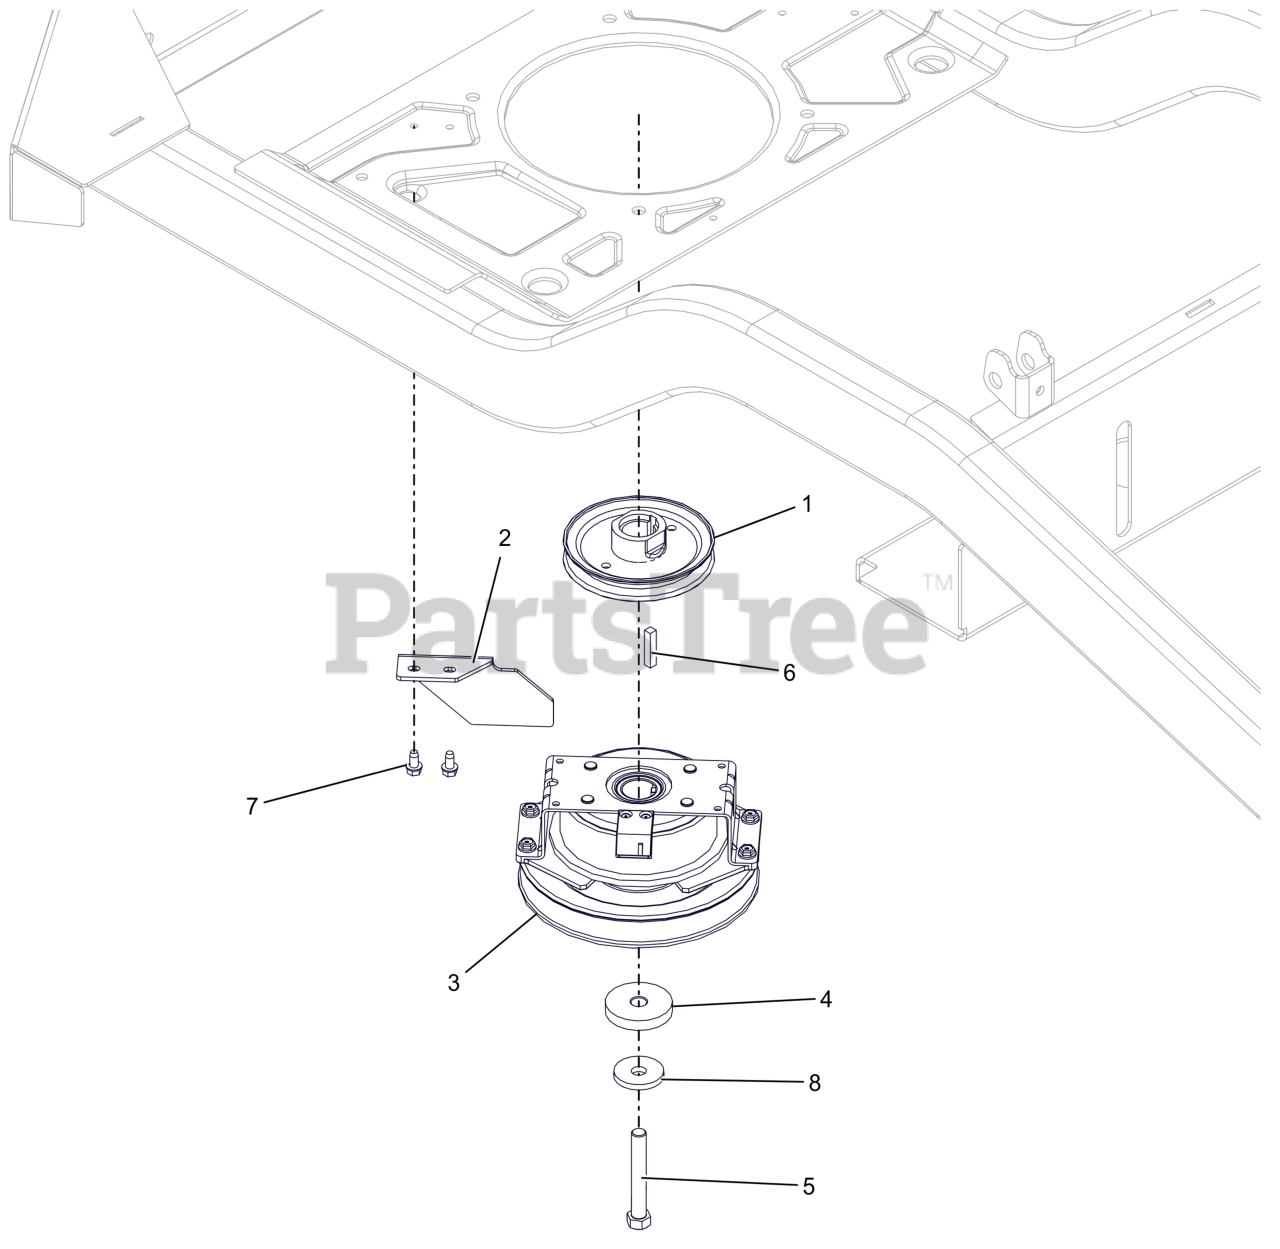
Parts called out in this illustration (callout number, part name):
1	WLDMT,PULLEY-4.50ODX1.003
2	BRKT, CLUTCH STOP HD
3	CLUTCH, OGURA DBL SPRG
4	SPACER, .474/.459X2.00X.350
5	BLT, HEX .44-20X3.00 G8 ZCC NT
6	KEY-SQ .25 X 1.25 X .25 SAE
7	SCR-TAP .25-20X.50 HWH ZCC
8	WASHER, 7/16" SPRING DISK
